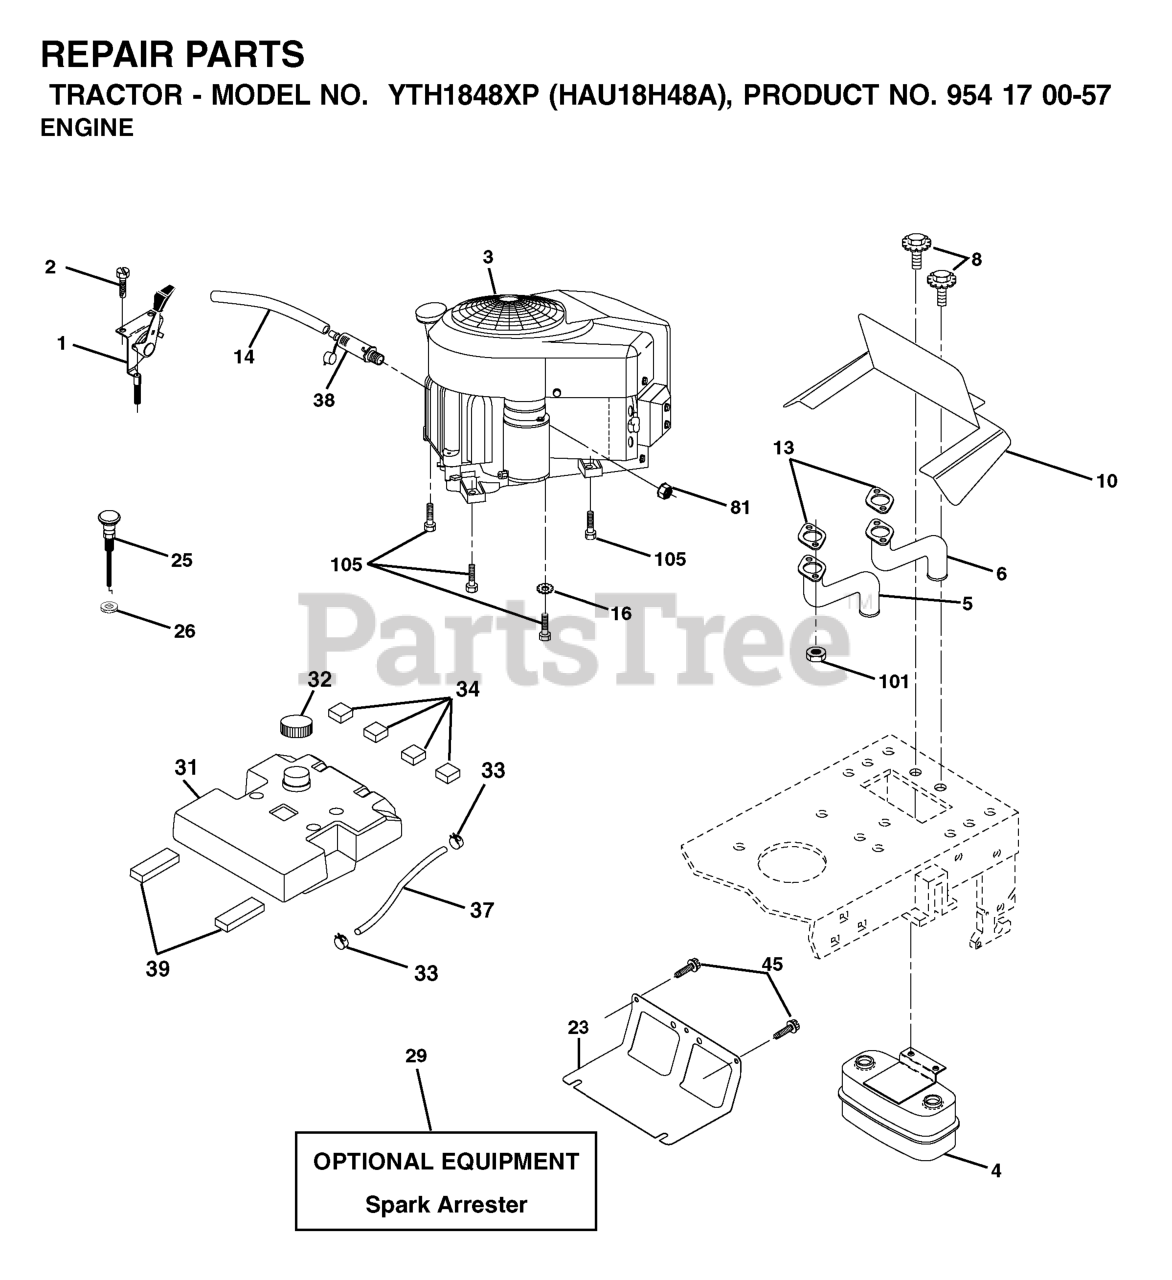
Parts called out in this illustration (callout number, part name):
1	CONTROL, THROTTLE
2	SCREW
4	MUFFLER.TWIN.CYL.LOW.TONE
5	EXHAUST.TUBE.LH.KAWASAKI.
6	EXHAUST.TUBE.RH.KAWASAKI.
8	BOLT.5/16-18UNCX3/4 W/SEMS.BLK
10	RP SHIELD HEAT MUFFLER
13	GASKET.EXHAUST.KAWASAKI.15-1
14	TUBE, DRAIN OIL ASM.
16	LOCKWASHER
23	SHIELD.BROWNING.DBR.GUARD
25	CHOKE CONTROL
26	Nut Keps 3/8 - 24 UNF
29	KIT.SPARK ARRESTOR 794945 B&S
31	TANK.FUEL(3.5.GAL)
32	FUEL CAP
33	HOSE CLAMP
34	PAD-SPACER LT
37	REPL BY 532 00 85-43
39	PAD IDLER TI
45	SCREW, 3/8-16X3/4
81	NUT
101	FLANGE NUT
105	SCREW 3/8-16X1
